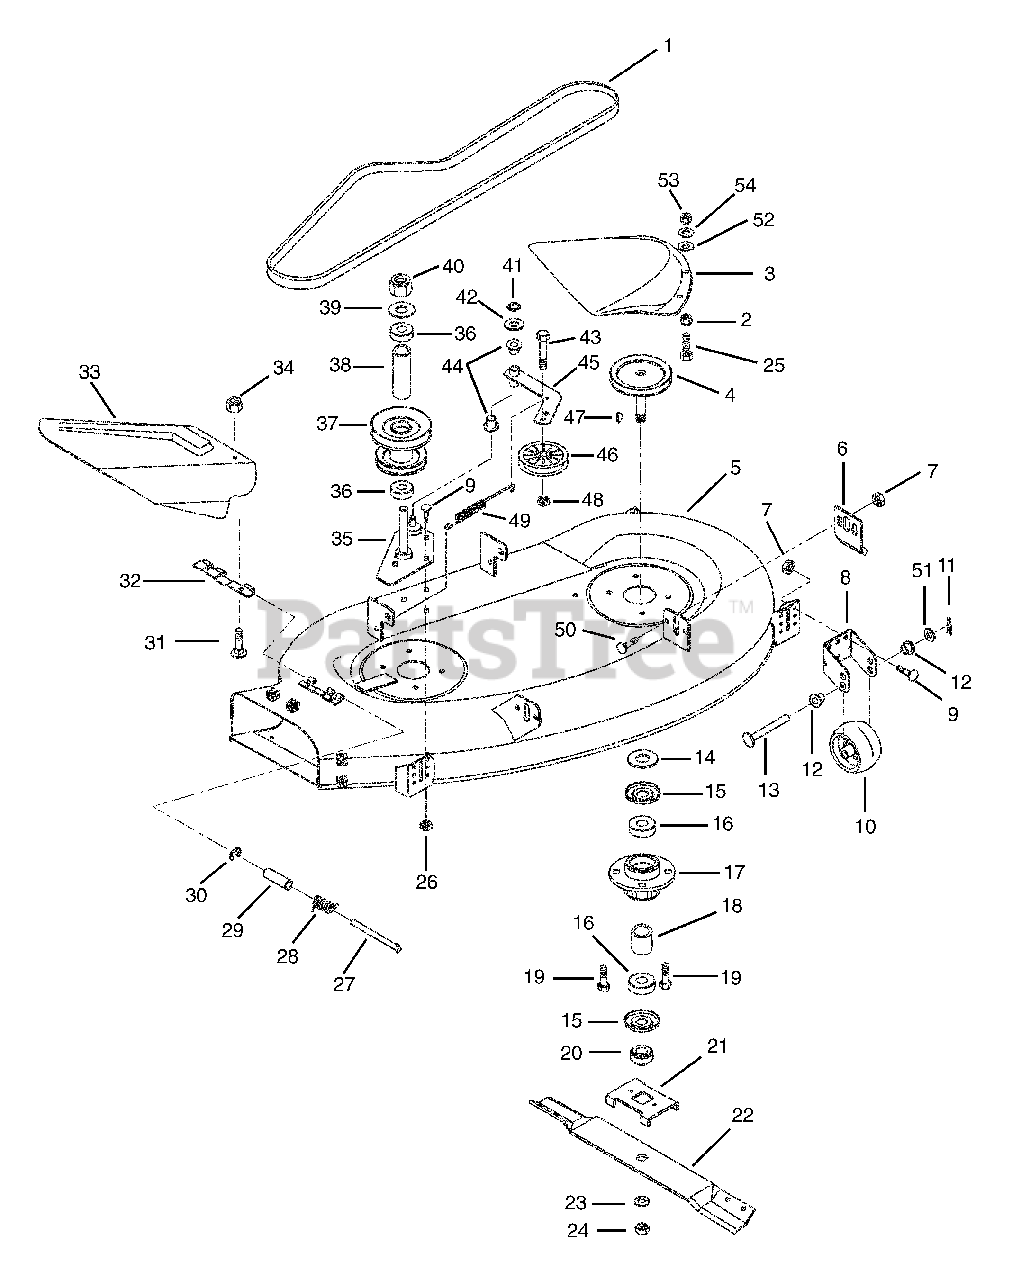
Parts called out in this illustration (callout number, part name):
1	V-BELT, 4L-RAW EDGE
2	@NUT-LK-CTR .38-16 YWZC
4	L. SPINDLE SHEAVE
4	R. SPINDLE SHEAVE
5	40" MOWER DECK W/DECALS
5	40" MOWER DECK ASSY COMPLETE
6	MOWER ADJUSTMENT TAB
7	@NUT-SPNLK-FLG .312-18 YWZC
8	CLEVIS
9	@BLT-RHDSSQNK .31-18X.62 G5YZ
11	PIN-HAIR INT .08X.18X1.18 YWZC
12	BSHG-FLG .372X.500X.312X.625NY
13	PIN-CLEV .371X3.25 YWZC
14	WSHR-FL-STL .755X1.25X.125 YZ
15	BEARING SLINGER
16	BRG-BALL .750X1.781X.61
17	SPINDLE HOUSING
18	SPACER .753X1.000X1.140
19	@BLT-RDHDSHSQNK.38-16X1.0 G5YZ
20	RETAINER HUB
21	BLADE TRAY 48
23	@WSHR-LK .75X.188 REG YWZC
24	NUT-JAM .75-10 YWZC
25	@BLT-HEX .38-16X1.00 GR5 YWZC
26	@NUT-SPNLK-FLG .312-18 YWZC
28	SG-TORS .095X.50X 1.0
29	BSHG-SLV .334 X .502 X 1.437
30	RG-RTNG-EXT .312X.025
31	BLT-RDHDSQSHNK.25-20X.50 YWZC
32	HINGE PLATE
33	40IN. CHUTE DEFLECTOR
34	@NUT-SPNLK-FLG .25-20 YWZC
35	MOUNT PLATE 40"
36	BRG-BALL .625X1.375X.44
37	JACKSHAFT PULLEY
38	SPACER .640X.880X2.545
39	WSHR-FL-STL .630X1.005X.062 YZ
40	@NUT-LK-NYL .625-18 YWZC
41	RG-RTNG-EXT .500X.042 (E)
42	WSHR-FL-STL .505X.880X.072 YWZ
43	@BLT-HEX .38-16X1.50 GR5 YWZC
44	BSHG-FLG.500X.625X.312X.750NY
45	IDLER ARM
46	IDLER-FLAT 3.00X.38
47	KEY-WDRF .188X.625X.31 SAE9MOD
48	@NUT-LK-CTR .38-16 YWZC
49	SG-TENS .113X.812X7.00
50	BLT-RDHDSQSHK.31-18X.75 GR2 YW
51	WSHR-PLASTIC .390X.875X.062
52	@WSHR-FL-STL.406X.812X.065 YWZ
53	@NUT-HEX .38-16 YWZC
54	@WSHR-LK .38X.094 REG YWZC
